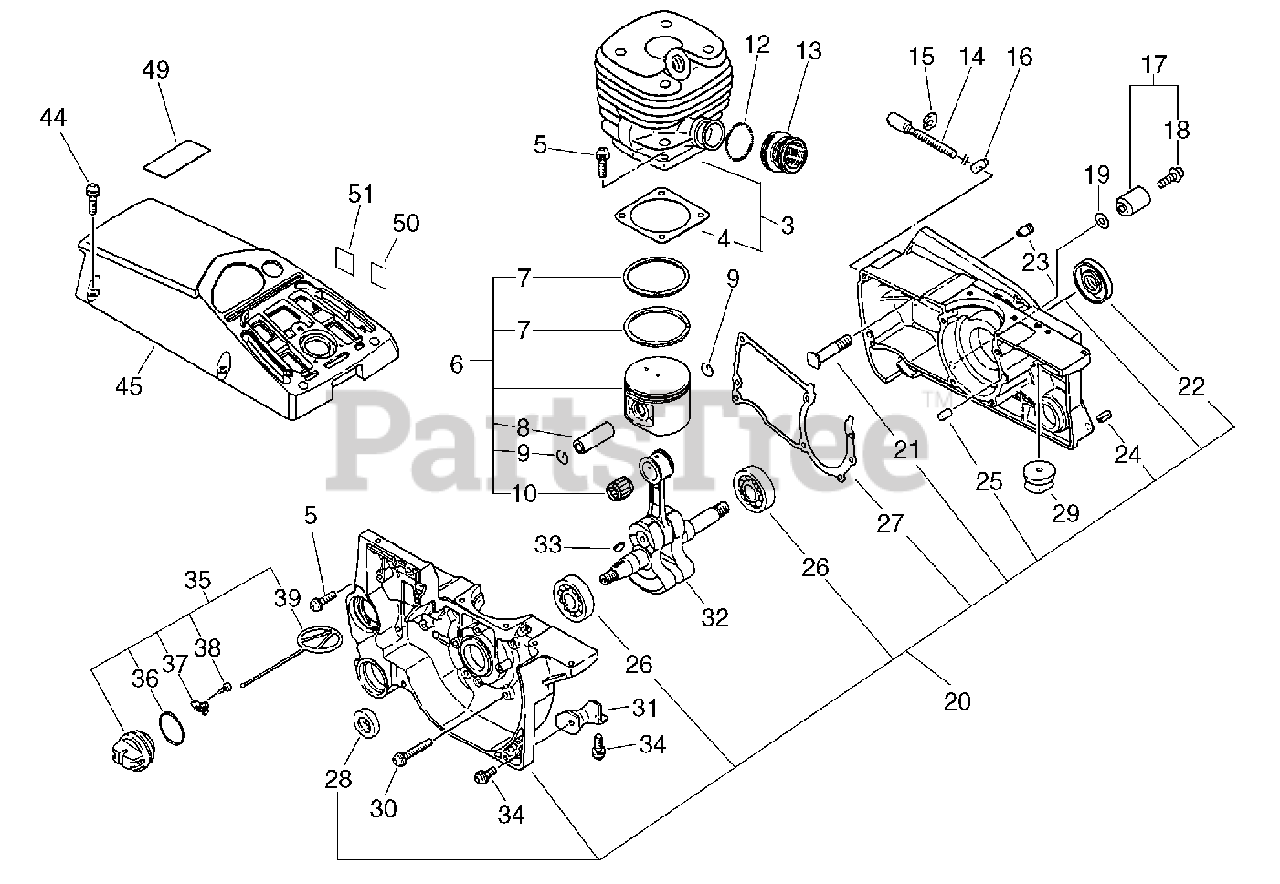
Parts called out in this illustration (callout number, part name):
3	CYLINDER KIT
4	GASKET, CYLINDER
5	BOLT 5×20
6	PISTON KIT
7	RING, PISTON
8	PIN, PISTON
9	RING, SNAP
10	BEARING, NEEDLE
13	ADAPTOR, INTAKE
14	SCREW, ADJUSTER
16	TENSIONER, CHAIN
17	CHAIN CATCHER KIT
18	SCREW 5×18
19	WASHER, FLAT 5.5×10×0.8
20	CRANKCASE KIT
21	STUD, GUIDE BAR 8
22	SEAL, OIL
23	VENT ASSY
24	PIN, SPRING 5×10
25	PIN, LOCATING 5×10
26	BEARING, BALL 6203 C3
27	GASKET, CRANKCASE
28	SEAL, OIL
30	BOLT M5×35
32	CRANKSHAFT
33	KEY, WOODRUFF
34	SCREW 5×14
35	CAP ASSY, OIL TANK
37	RETAINER, CONNECTOR
38	SCREW, TAPPING 3×8
39	CONNECTOR, CAP L= 60 MM
44	SCREW 5×20
45	COVER, CYLINDER
49	LABEL, CAUTION
50	LABEL, CAUTION
51	LABEL, ADJUSTING
